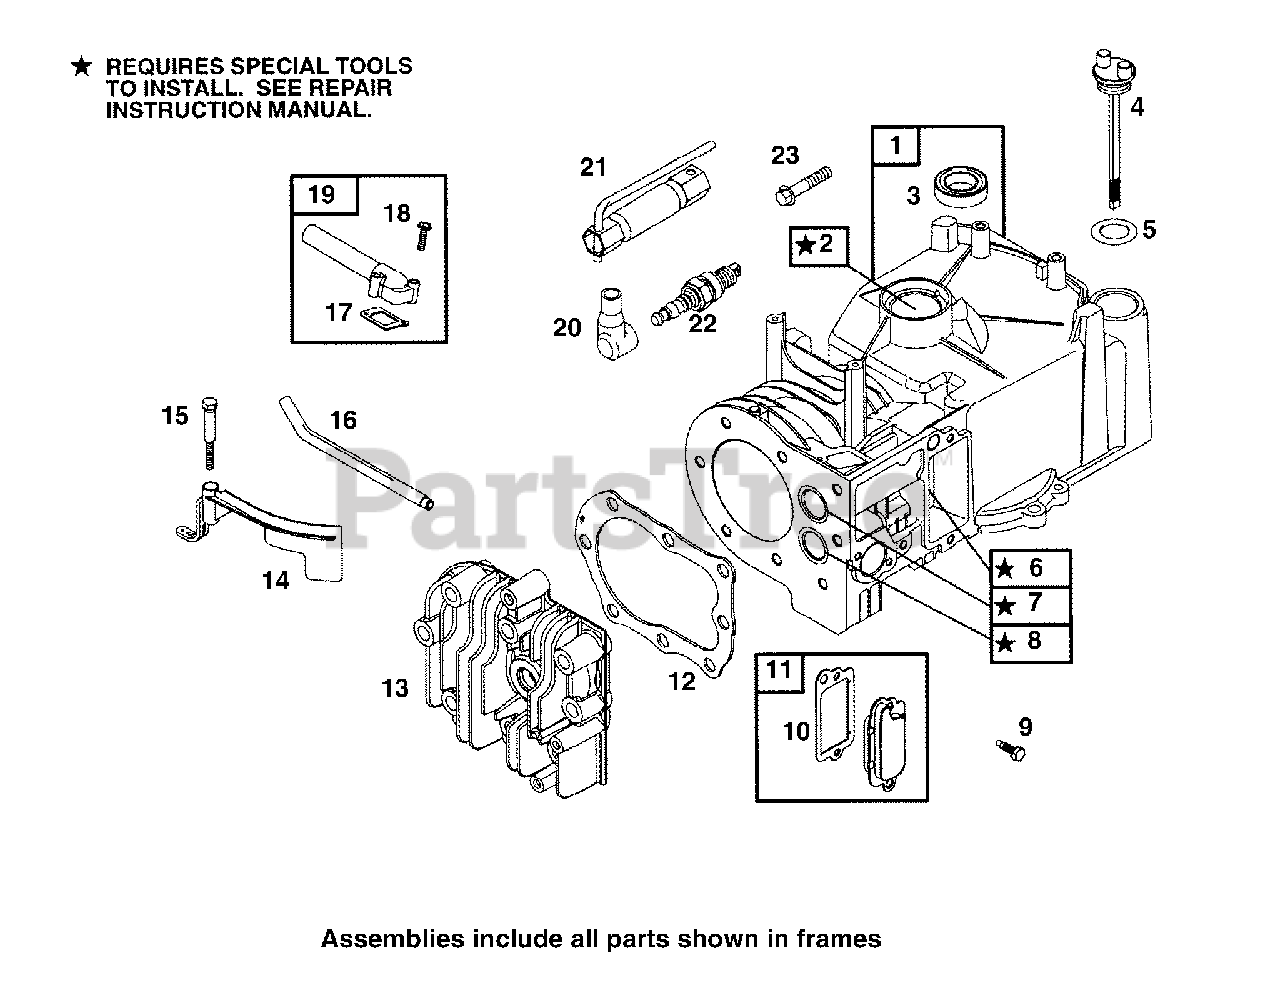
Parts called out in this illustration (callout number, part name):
1	Cylinder Assembly
2	Bushing
3	Oil Seal
4	Dipstick
5	O-Ring Seal
6	Guide Bushing (Exhaust)
7	Valve Seat (Intake)
8	Valve Seat (Exhaust)
9	Hex Screw
10	Breather Gasket
11	Breather Assembly
12	Cylinder Head Gasket
13	Cylinder Head
14	Governor Blade
15	Shoulder Screw
16	Breather Tube
17	Intake Gasket
18	Hex Screw
19	Intake Manifold
20	Spark Plug Boot
21	Spark Plug Wrench
22	Spark Plug
23	Hex Screw
